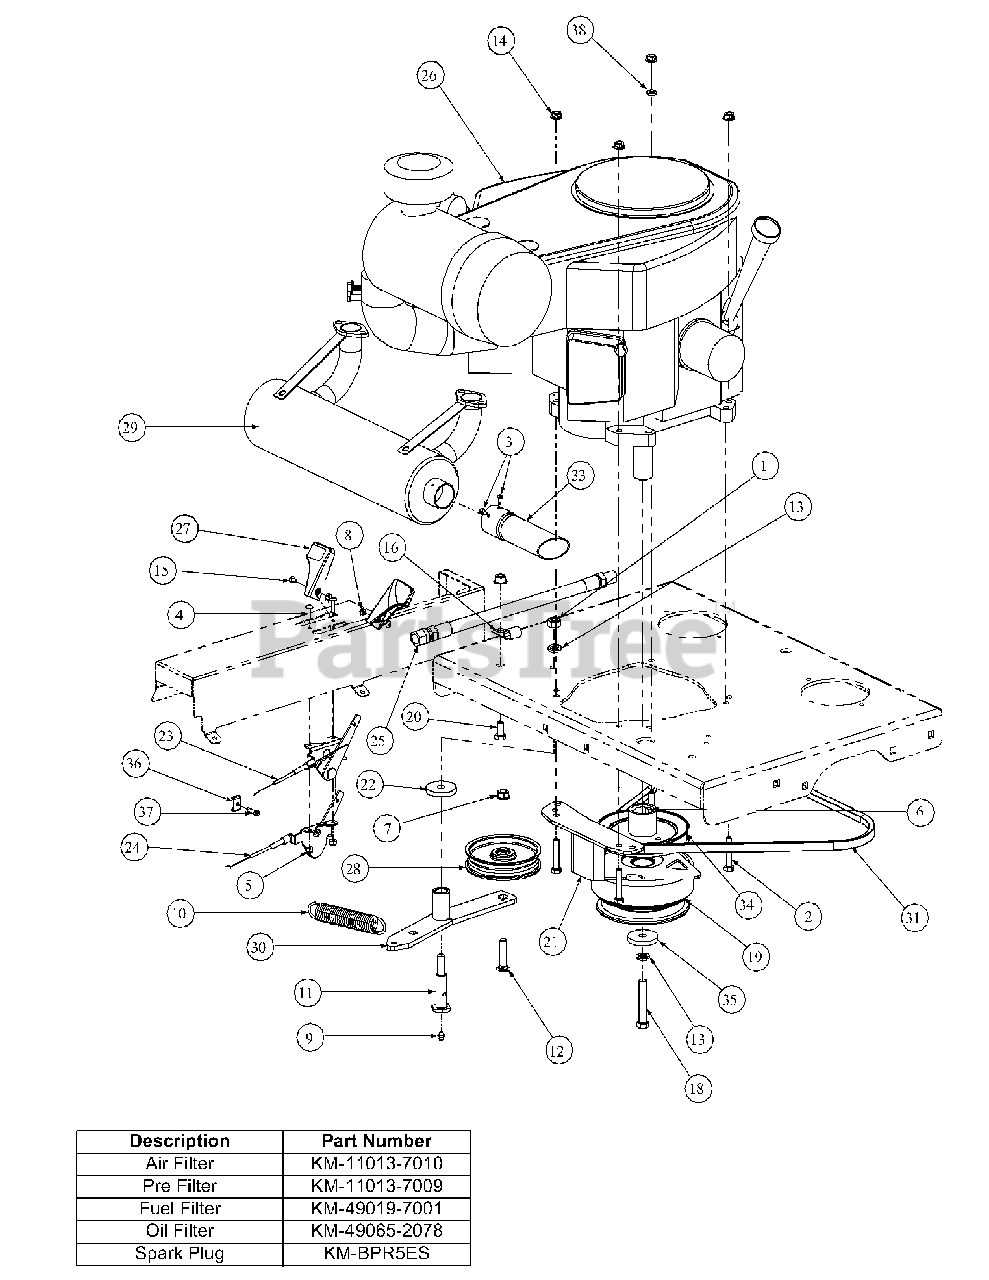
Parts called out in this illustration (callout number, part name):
1	Hex Nut, 7/16-14
2	HHCS, 5/16-18, 1-3/4
3	Screw, #8-32 x 0.375
4	Round Hd. Machine Screw, 10-32 x 3/4
5	Lock Nut, Nylon Insert, 10-32
6	Key, 1/4 x 1/4 x 3
7	Flange Lock, Hex Nut, 3/8-16
8	Nut Washer, W/Star, 8-32
9	Grease Fitting, 1/4-28 x 3/16
10	Extension Spring, 1.0 OD x 5.125
11	Shoulder Screw, 7/16-14
12	Hex Carriage Screw, 3/8-16, 1.75
13	Lock Washer, 7/16
14	Hexflange Lock Nut, 5/16-18
15	Machine Screw, 8-32, .375
16	Clip, Heat Shield Cable
18	Capscrew, 7/16-20 x 2.50
19	Clutch Brake, 1.125 ID
20	Hex Cap Screw, 3/8-16, .750
21	Retainer Clutch Assembly, Ogura
22	Flat Washer, 7/16 ID x 1.75 OD x .25
23	Choke, Control Cable, 43.0
24	Throttle, Control Cable, 39.0
25	Oil Drain Hose
26	19HP Twin Engine, Kawasaki
27	Control Throttle Knob
28	Flat Pulley with Flanges
29	Muffler Accessory, Kawasaki
30	Engine Idler Arm Assembly
30	Bearing
30	Engine Idler Arm Assembly Cast
31	V Belt, A Section x .47.3
33	Muffler Accessory Exhaust Tube
34	Pump Drive Pulley
35	Flat Washer, 7/16 ID x 1.75 OD x .25
36	Bolt, M5 x 18
37	Choke Cable Clamp
38	Flat Washer, .320 ID x .591 OD x .078
